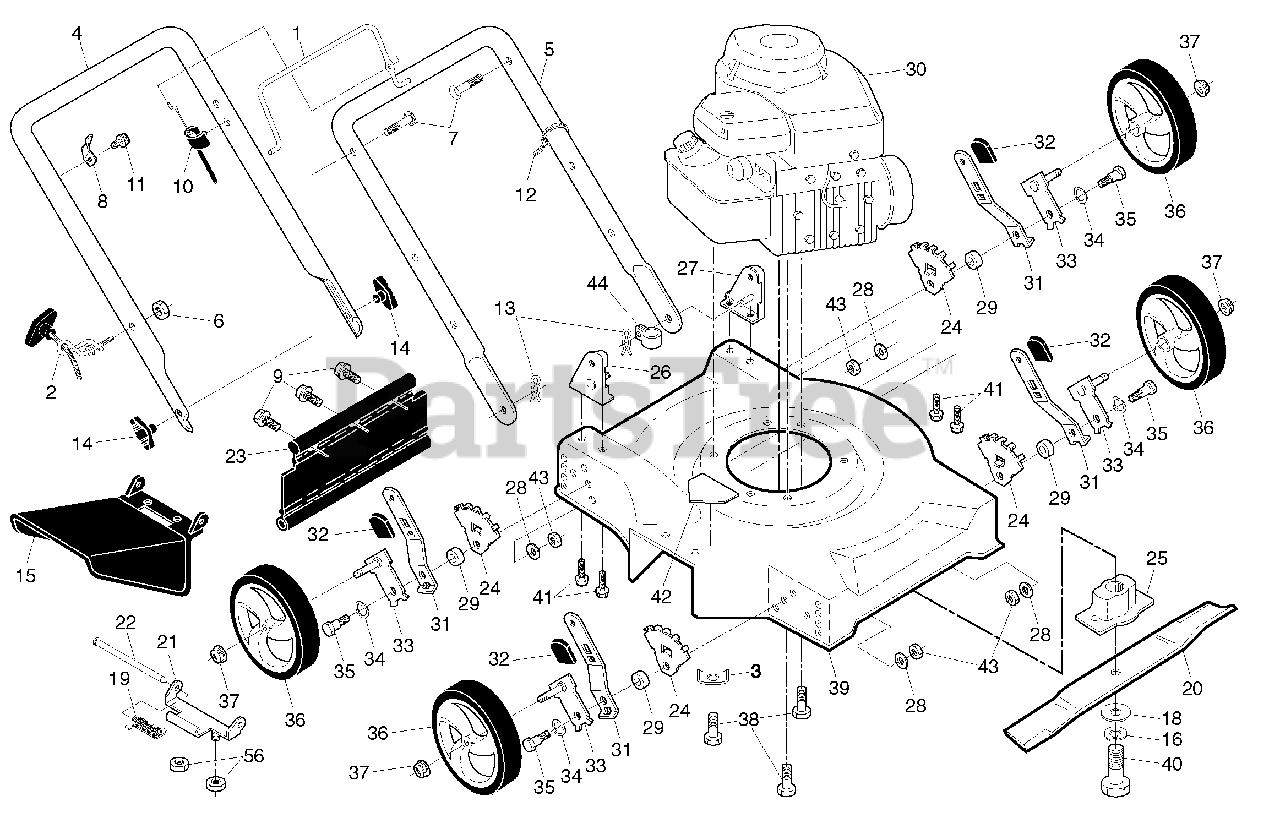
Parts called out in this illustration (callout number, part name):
1	Control Bar
2	Rope Guide
4	Upper Handle
5	Lower Handle
7	Handle Bolt 5/16-18 x 1-3/4
8	Up-Stop Bracket
9	Hex Washer Head Screw #10-24 x 1/2
10	Engine Zone Control Cable
11	Screw
12	Wire Tie
13	Hairpin Cotter
14	Knob, Handle
15	Discharge Guard
16	Helical Lock Washer 3/8
18	Hardened Washer
19	Torsion Spring
20	Blade, 20"
21	Hinge Deflector
22	Hinge Rod
23	Rear Deflector
24	Wheel Adjusting Bracket
25	Blade Adapter
26	Handle Bracket Assembly, RH
27	Handle Bracket Assembly, LH
28	Washer, Flat
29	Spacer
31	Selector Spring
32	Selector Knob
33	Axle Arm Assembly
34	Belleville Washer
35	Shoulder Bolt
36	Wheel and Tire Assembly
37	Nut, Hex
38	Hex Head Thread Rolling Screw 3/8-16 x 1-1/8
39	Lawn Mower Housing
40	Hex Head Screw 3/8-24 x 1-3/8 Grade 8
41	Thread Cutting Screw 5/16-18 x 3/4
42	Danger Decal
43	Locknut, Hex 5/16-18
44	Clip, Cable
56	Locknut, Hex 1/4-20
56	Operator's Manual, English
56	Operator's Manual, French
56	Repair Parts Manual, English
